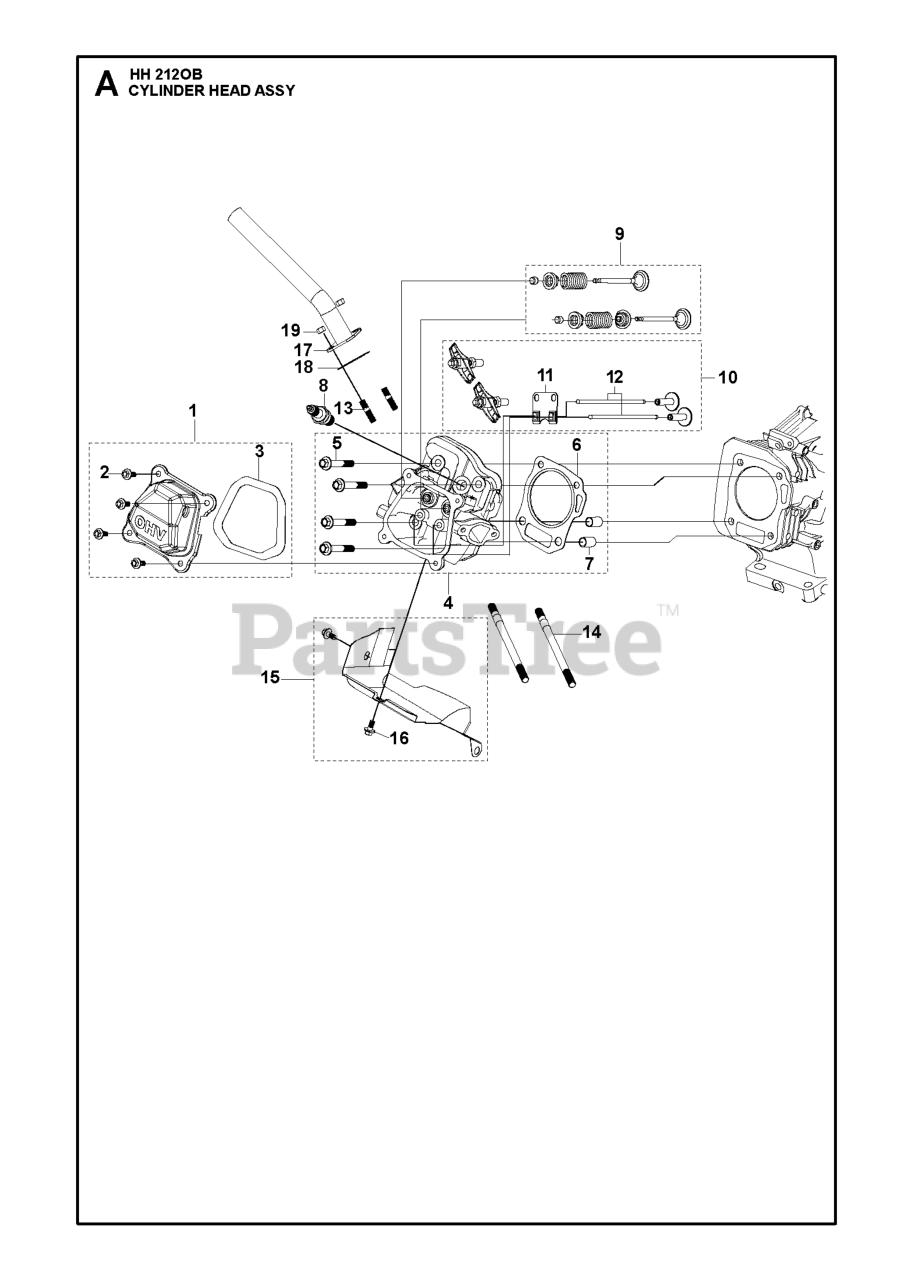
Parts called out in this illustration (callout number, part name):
7	PIN LOCATION PIN
8	SPARK PLUG HQT-7 RESISTOR
16	Husqvarna TBD
